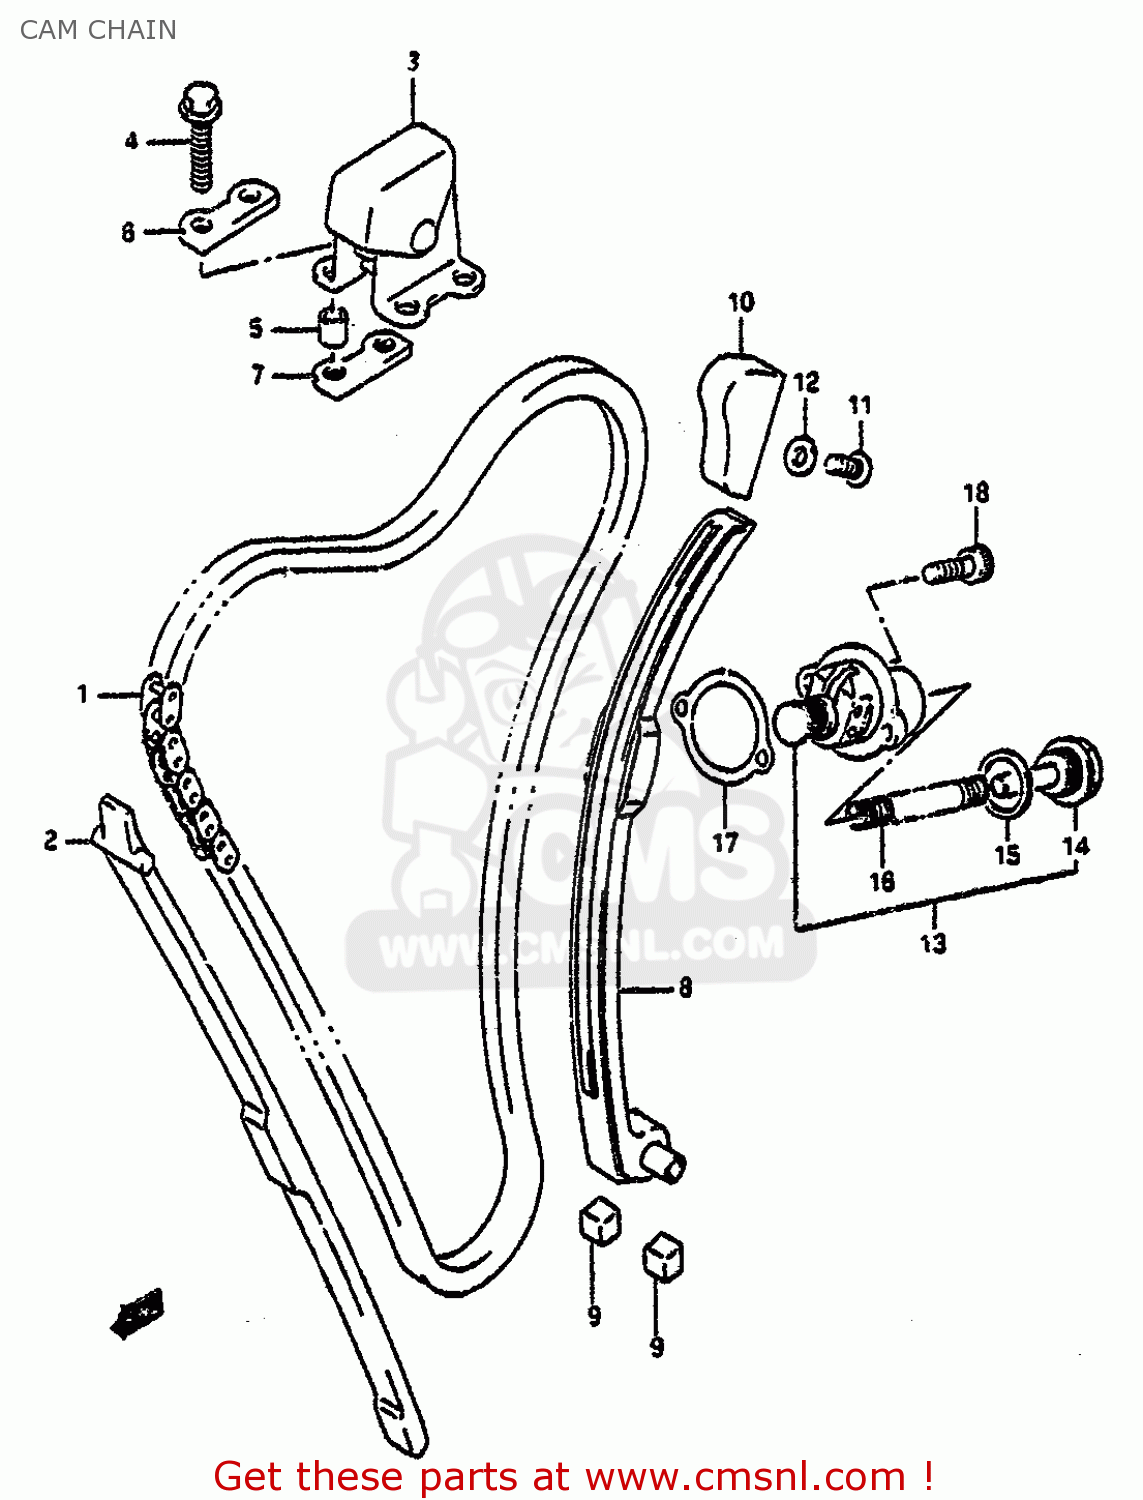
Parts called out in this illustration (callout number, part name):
1	CHAIN,CAMSHAFT DRIVE
2	GUIDE,CAM CHAIN NO.1
3	IDLER,CAM CHAIN
4	BOLT
5	SPACER (6,8X10X9.4)
6	CUSION,IDLER
7	CUSHION,IDLER
8	TENSIONER,CAM CHAIN
9	CUSHION,CAM CHAIN TENSIONER
10	GUIDE,CAM CHAIN NO.2
11	BOLT
12	GASKET(5.8X13X1.2) (NAS)
13	ADJUSTER ASSEMBLY,TENSIONER
14	PLUG
15	GASKET (NAS)
16	SPRING
17	GASKET,TENSIONER ADJUSTER (NAS)
18	BOLT
